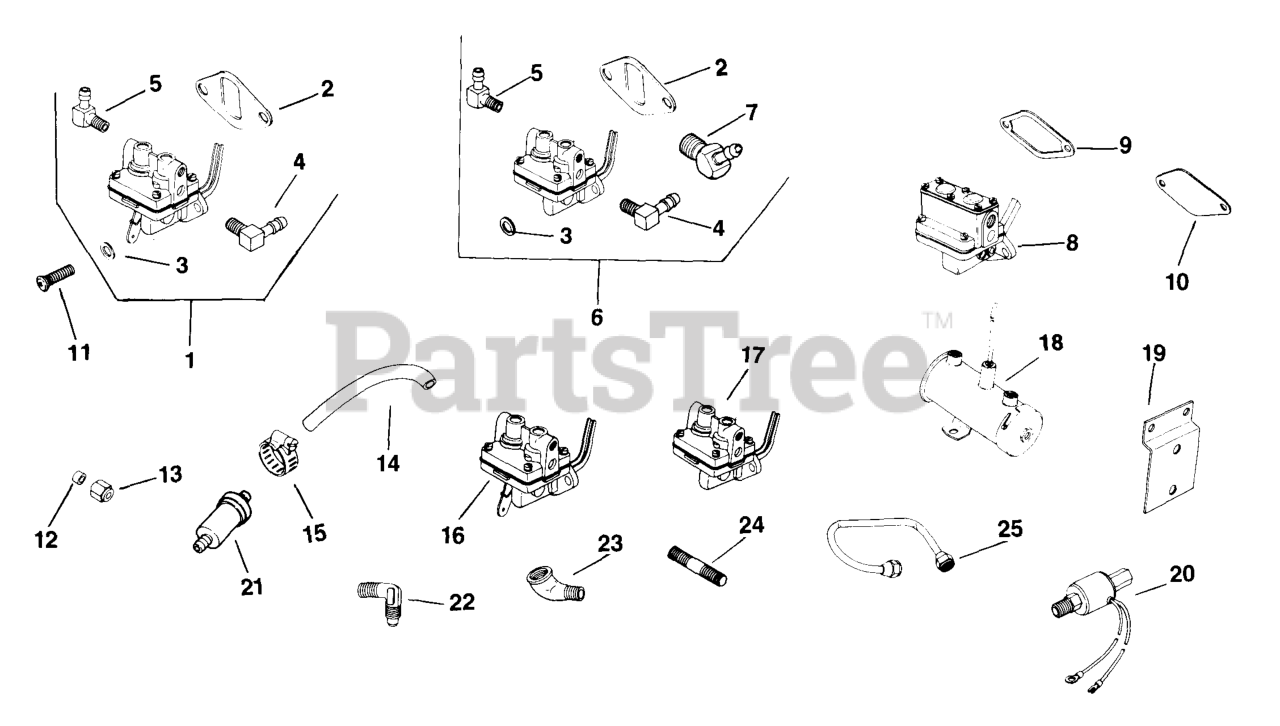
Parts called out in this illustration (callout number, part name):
2	GASKET - USE 25 041 09
4	CONNECTOR, 90 DEG. HOSE
11	SCREW, SEMS 1/4-20X3/4"
14	LINE
15	CLAMP, HOSE 1/2" USE 25 237 14-S
17	KIT, FUEL PUMP USE 47 559 11-S
230675-S	KIT, FUEL PUMP REPAIR - DISC.
